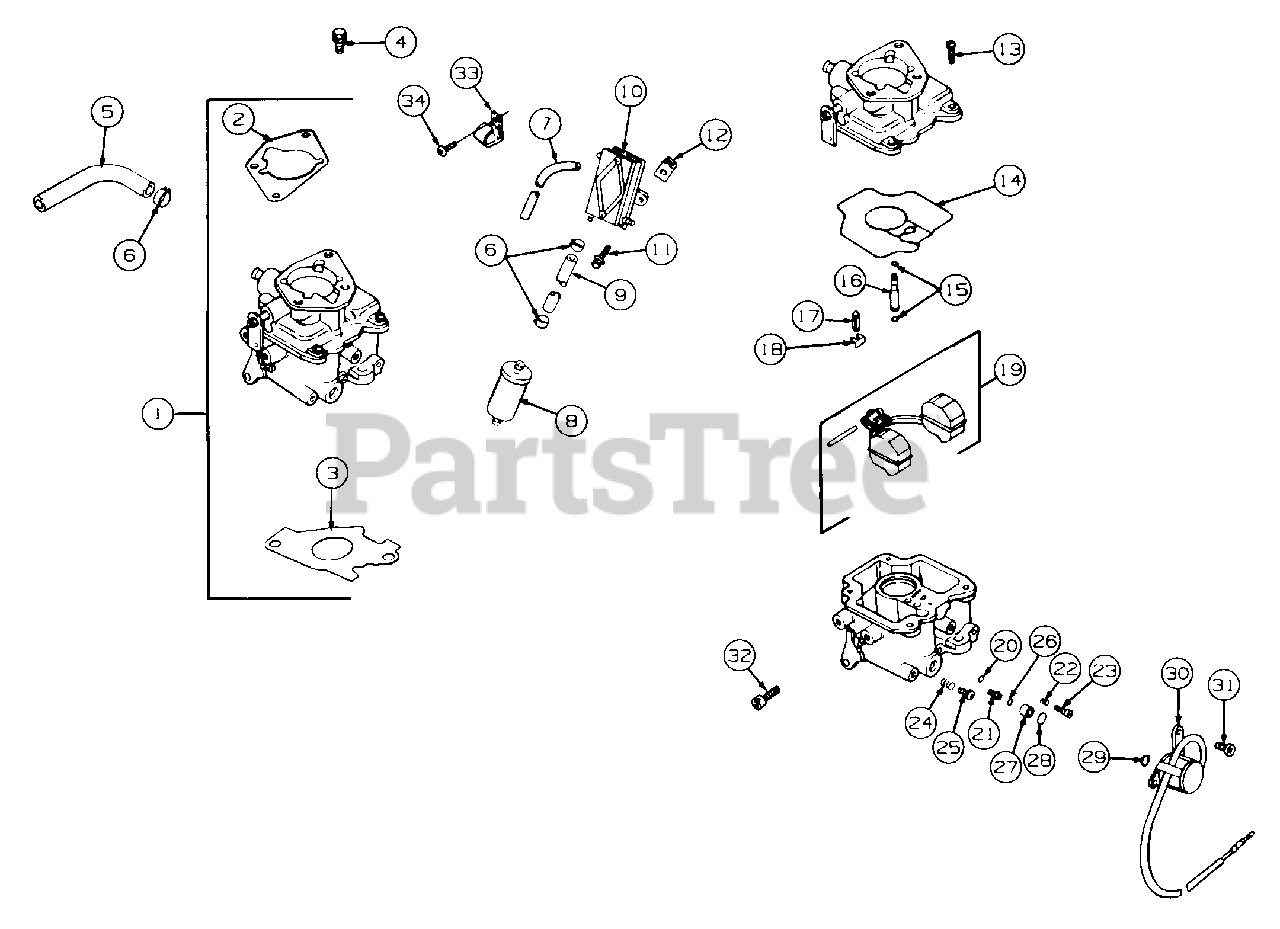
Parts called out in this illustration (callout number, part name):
1	Kit, Carburetor
2	Gasket, Air Cleaner
3	Gasket, Carburetor
4	Screw, M6 x 1.0 x 18
5	Line, Fuel, 9"
6	Clamp, Hose
7	Line, Fuel 15.5"
8	Filter, Fuel
9	Line, Fuel, 10"
10	Pump, Fuel-Pulse
11	Screw, Hex Cap
12	Nut
13	Screw, Carburetor Body
14	Gasket, Carburetor Body
15	O-Ring, Slow Jet
17	Valve, Inlet Needle
18	Clip, Inlet Needle Valve
19	Kit, Float Repair
20	O-Ring, Main Jet
22	Spring, Idle Adjust
23	Needle, Idle Adjust
24	Spring, Idle Speed Adjust
25	Screw, Idle Speed Adjust
27	Seat, Solenoid
29	O-Ring, Solenoid
30	Solenoid
32	Screw, Throttle Stop
33	Clip, Cable
34	Screw, M6 x 1.0 x 1.0
